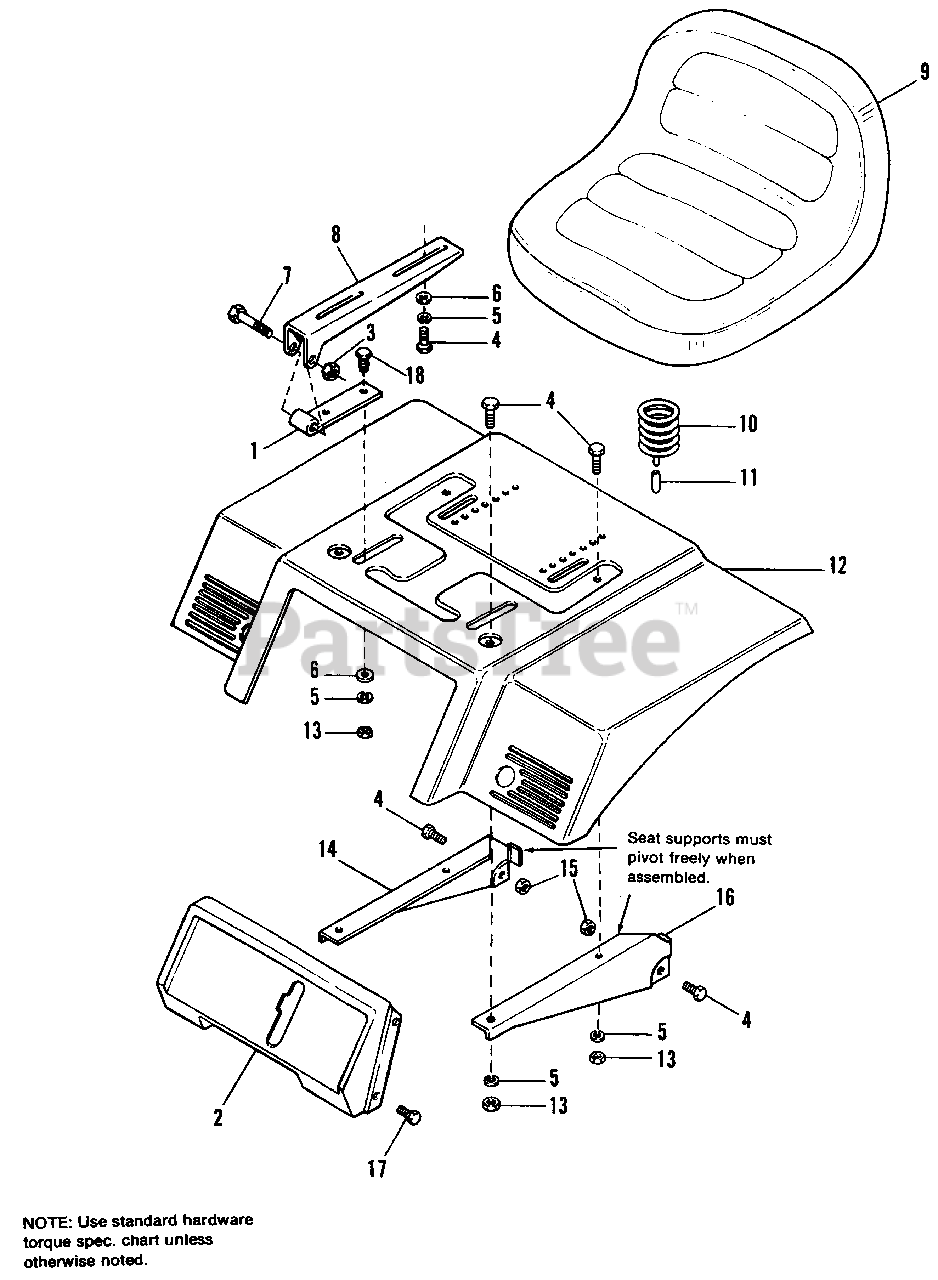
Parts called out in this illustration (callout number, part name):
1	HINGE, Lower
2	PANEL, Shift
3	NUT, Hex, Lock, 3/8-16
4	CAPSCREW, Hex, 5/16-18 x 3/4
5	LOCKWASHER, 5/16
6	WASHER, 5/16
7	CAPSCREW, 3/8-16 x 2
8	HINGE, Upper
10	SPRING, Seat
11	COVER, Wire
12	DECK, Seat
13	NUT, Hex, 5/16-18
14	SUPPORT, Seat, R.H.
15	NUT, Hex, Lock, 5/16-18
16	SUPPORT, Seat, L.H.
17	SCREW, Taptite, 1/4-20 x 1/2
18	CAPSCREW, Hex, 5/16-18 x 1
